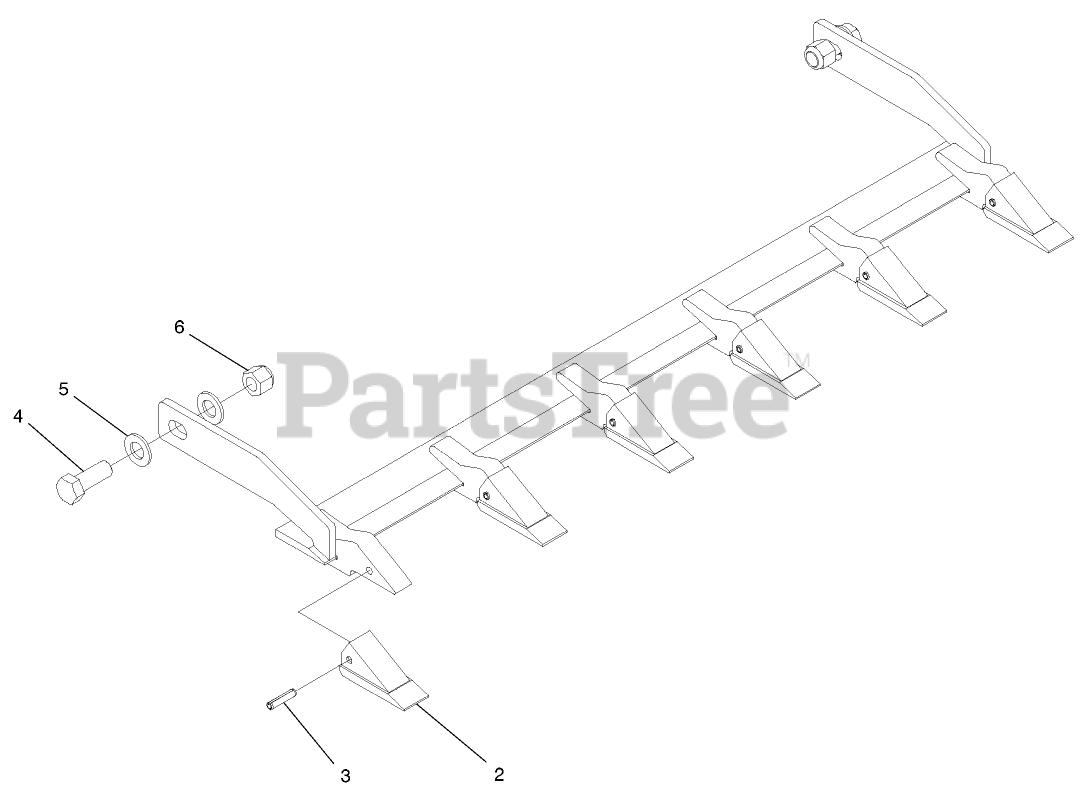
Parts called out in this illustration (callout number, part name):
2	TOOTH-BUCKET
3	PIN-ROLL
4	SCREW-HH
5	WASHER-FLAT
6	NUT-LOCK, NI
